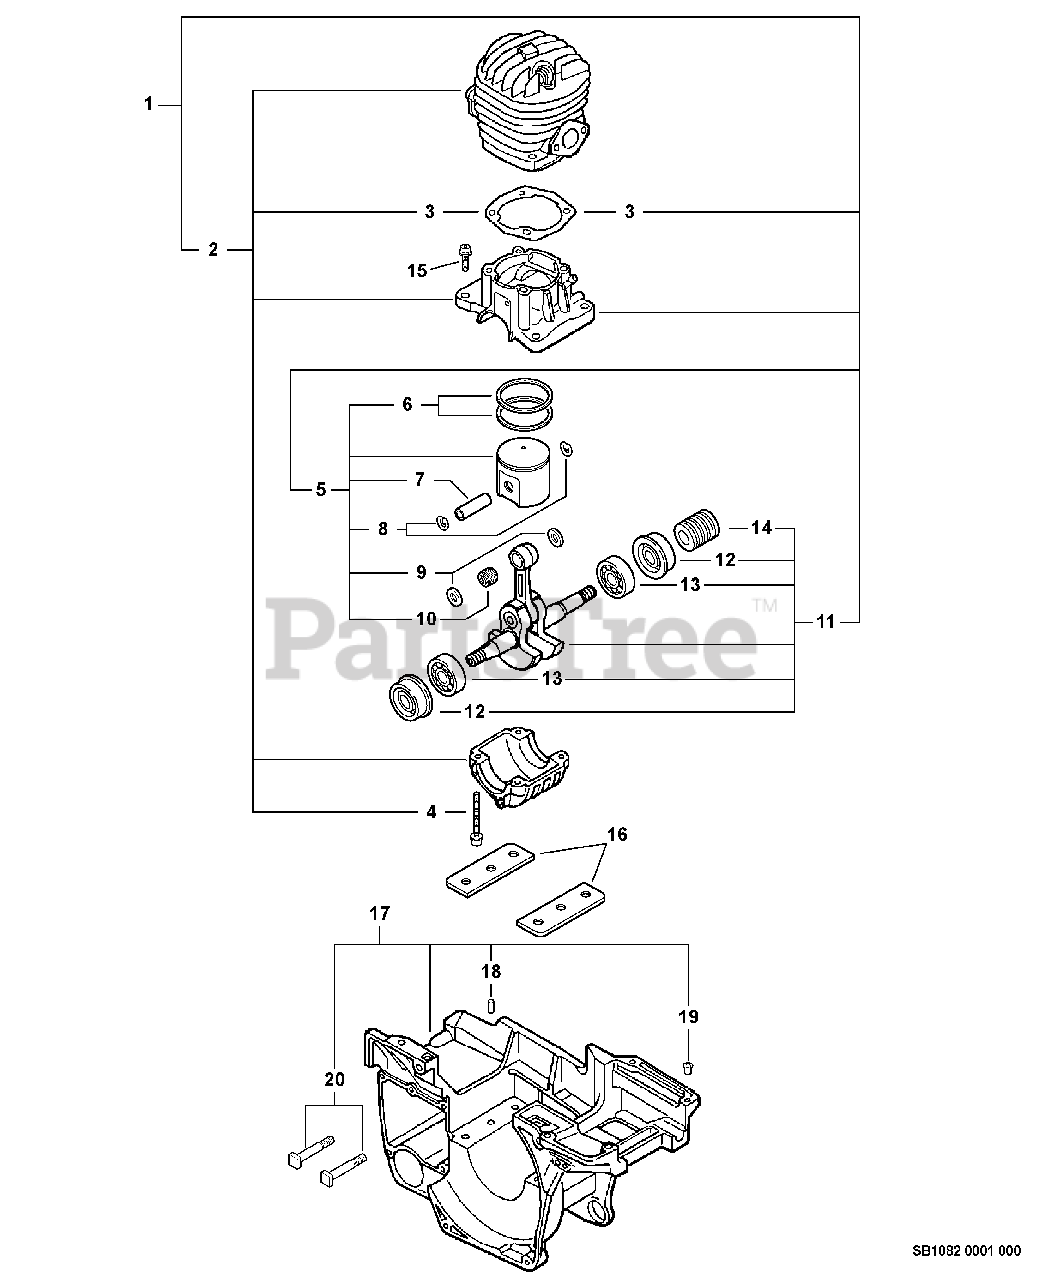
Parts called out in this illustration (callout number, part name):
1	SHORT BLOCK -- SB1082
2	CRANKCASE KIT
3	GASKET, CYLINDER
4	SCREW - 5X55
5	PISTON KIT
6	RING, PISTON
7	PIN, PISTON
8	RING, RETAINING
9	BEARING, NEEDLE
10	SPACER, PISTON
11	CRANKSHAFT ASSY
12	SEAL, OIL - 12
13	BEARING, BALL - 6201
14	GEAR - WORM
15	SCREW - 5X22
17	ENGINE COVER ASSY
18	PIN - LOCATING
20	STUD, GUIDE BAR
